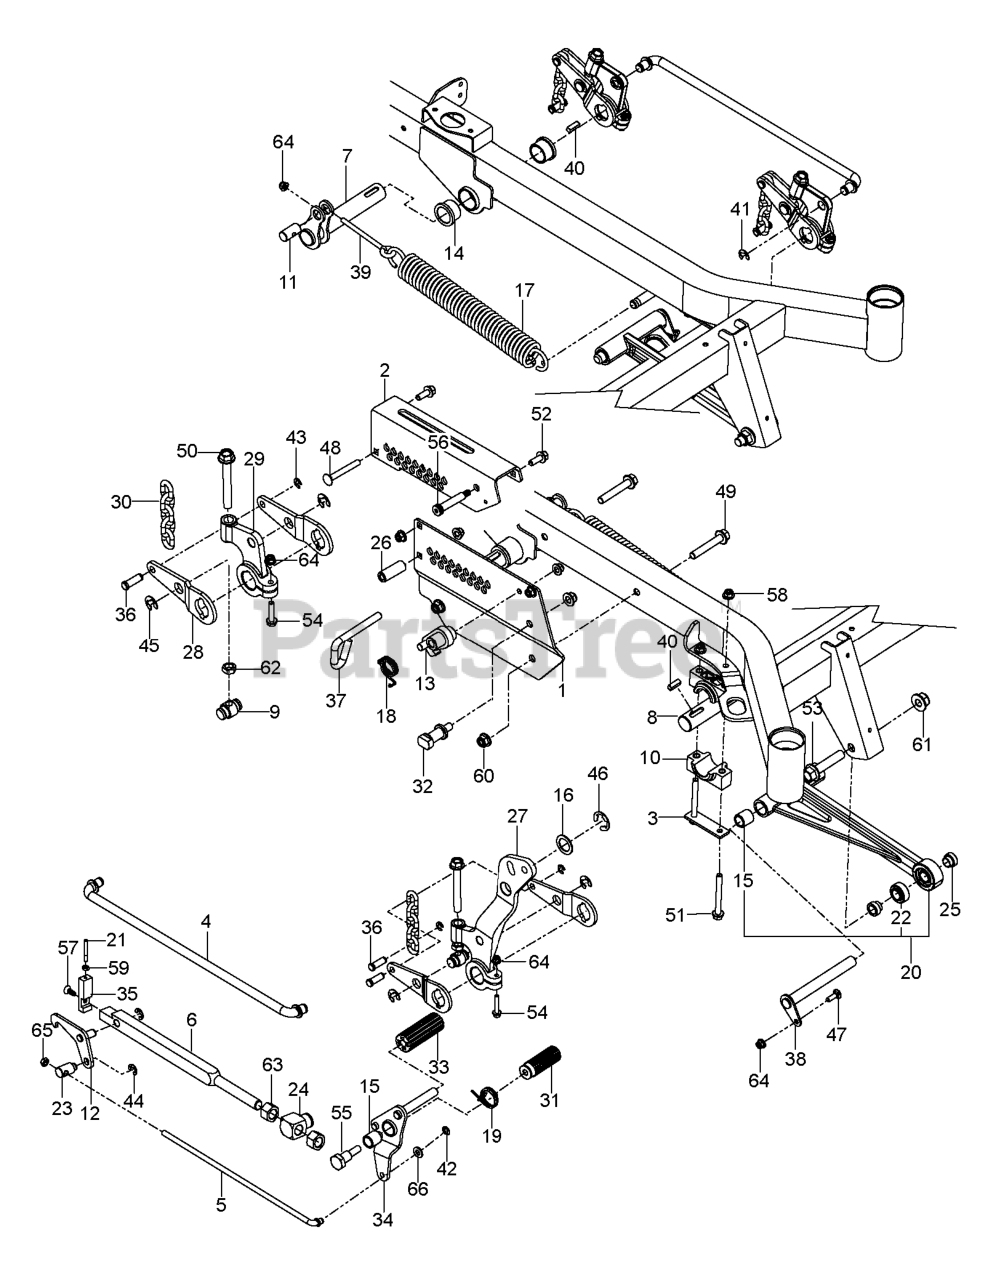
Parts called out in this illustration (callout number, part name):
1	PLATE, INNER HEIGHT, ORANGE
2	PLATE, OUTER HEIGHT ORG
3	PLATE, PILLOW BLACK
5	ROD, HEIGHT LATCH
6	BAR, HEIGHT
7	SHAFT, RR LIFT
8	SHAFT, LIFT, FT
9	SHAFT, LIFT TRUNION WSL
10	BLOCK, PILLOW
11	PIVOT, SPRING
12	LATCH, HEIGHT WLDMT
13	LATCH, TRANSPORT WLDMT
14	BUSHING, FLANGE 1.25 X 1.0
15	BUSHING, SLEEVE 3/4 X 1.0
16	MACHINE BUSHING
17	SPRING, EXTENSION
18	SPRING, TORSION
19	SPRING, TORSION
20	ASSEMBLY, STRUT
21	LINK, INDICATOR
22	BALL JOINT, 3/4" SWIVEL
23	SWIVEL, HEIGHT LATCH
24	SWIVEL, HEIGHT BAR
25	SPACER, STRUT
26	SPACER, HEIGHT PLATE
27	ARM, LIFT LEVER
28	ARM LIFT BLK
29	ARM, CAST LIFT
30	LIFT CHAIN
31	PAD, FOOT PEDAL
32	GUIDE, HEIGHT BAR
33	PEDAL, DECK HEIGHT
34	PEDAL, RELEASE WLDMT
35	CAP, HEIGHT BAR
36	PIN, 7/16 CLEVIS
37	PIN, HEIGHT
38	PIN, STRUT
39	EYE BOLT 4.5`
40	KEY, 5/16 SQ X 1.0
41	E-RING 5/8
42	E RING 3/8"
43	RING, E, 7/16
44	E-RING 1/2 (2 2)
45	E RING 3/4
46	E-RING 1"
47	RHSNB 5/16C X 1
48	3/8-16 X 3` CARR BOLT
49	HFFS 1/2-13 X 3 GD 5 ZD
50	HHFS 1/2-13 X 4 GR 5
51	HHFS 3/8-16 X 3.5 GD 5 ZD
52	HHFS 3/8-16 X 1 GRD 5 ZD
53	HHFS 5/8-11 X 3.0 GD 8 ZD
54	HHFS 5/16-18 X 1.5 GD 5
55	BOLT, SHOULDER
56	BOLT, SHOULDER, 1/2 X 2.25
57	SCREW, 5/16-18 X 3/4 FLAT HEX
58	NUT 3/8-16 HEX FLG NYLOC ZD
59	NUT 1/4-20 JAM
60	NUT, 1/2-13 HEX FLG NYLOC ZD
61	NUT 5/8-11 FLG NYLOC ZD
62	NUT 1/2 HEX JAM
63	NUT 3/4-10 HEX ZD
64	5/16-18 NYLOC FLANGE NUT
65	NUT 3/8-24 JAM
66	WASHER 3/8 SAE FLAT
